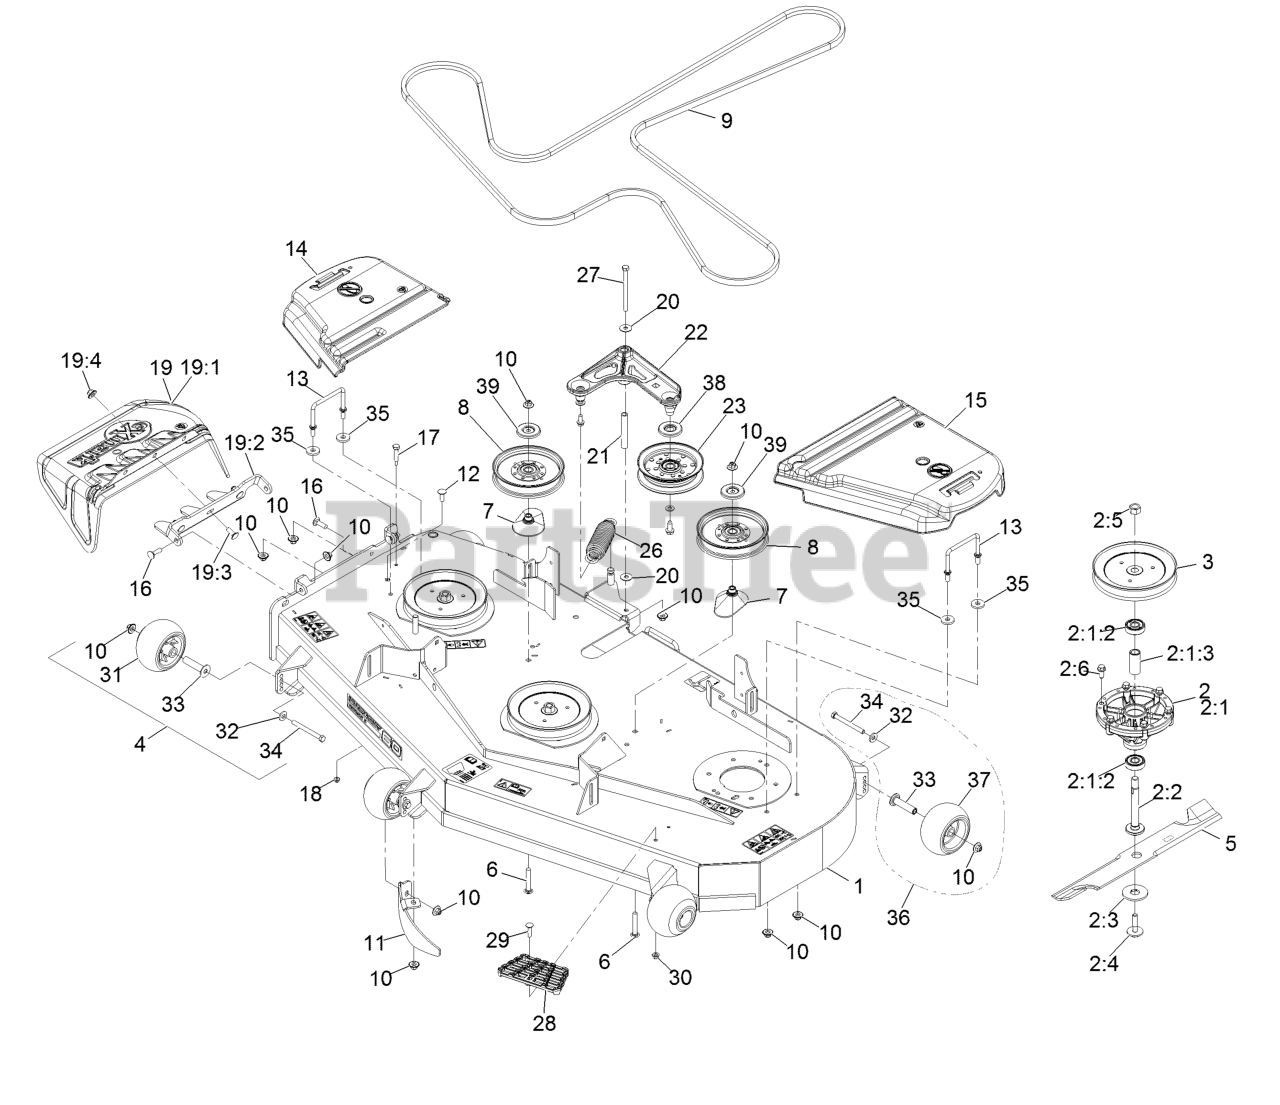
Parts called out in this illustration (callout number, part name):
1	ASM-Deck W/Decals 603
2	ASM, Cutter Housing Complete
2:1	ASM-Cutter Housing
2:1:2	Bearing
2:1:3	Spacer-Bearing
2:2	Spindle-Hex Pilot
2:3	Washer-Hex Blade Drive
2:4	Bolt-Blade, Sem
2:5	Nut-Hex
2:6	Screw-Forming, Thread
3	Sheave,Blade Drive 7.25
4	Kit, Anti-Scalp Roller
5	Blade, Notched
5	Blade-Extreme 2, 20.50"
5	Blade, Mulching
5	Blade, Low Lift
5	Blade, Solid
6	Screw-CARR
7	Spacer-Pulley
8	Idler-Pulley, Flat 6.00X1.00
9	Belt-V
10	Nut-Flange, NI
11	Dogleg-603
12	Screw-CARR
13	Wireform-Cover
14	Cover-Belt, RH
15	Cover-Belt, LH
16	Bolt-CARR
17	Bolt-Shoulder
19	ASM,Discharge Chute
19:1	Chute, Discharge
19:2	Bracket,Discharge Chute
19:3	Screw-CARR
19:4	Nut-Flange, NI
21	Bushing
22	Idler Arm ASM
23	Idler-Pulley, Flat
26	Spring-Extension
27	Screw-HH
28	Step-Deck
29	Screw-CARR
30	Nut-HF, NI
31	Roller-Anti-Scalp
32	Washer-Belleville
33	Axle, Roller
34	Screw-HH
36	Kit-Antiscalp Roller
37	Roller-Scalp, Anti
38	Shield-Guard, Dust
39	Shield-Dust
